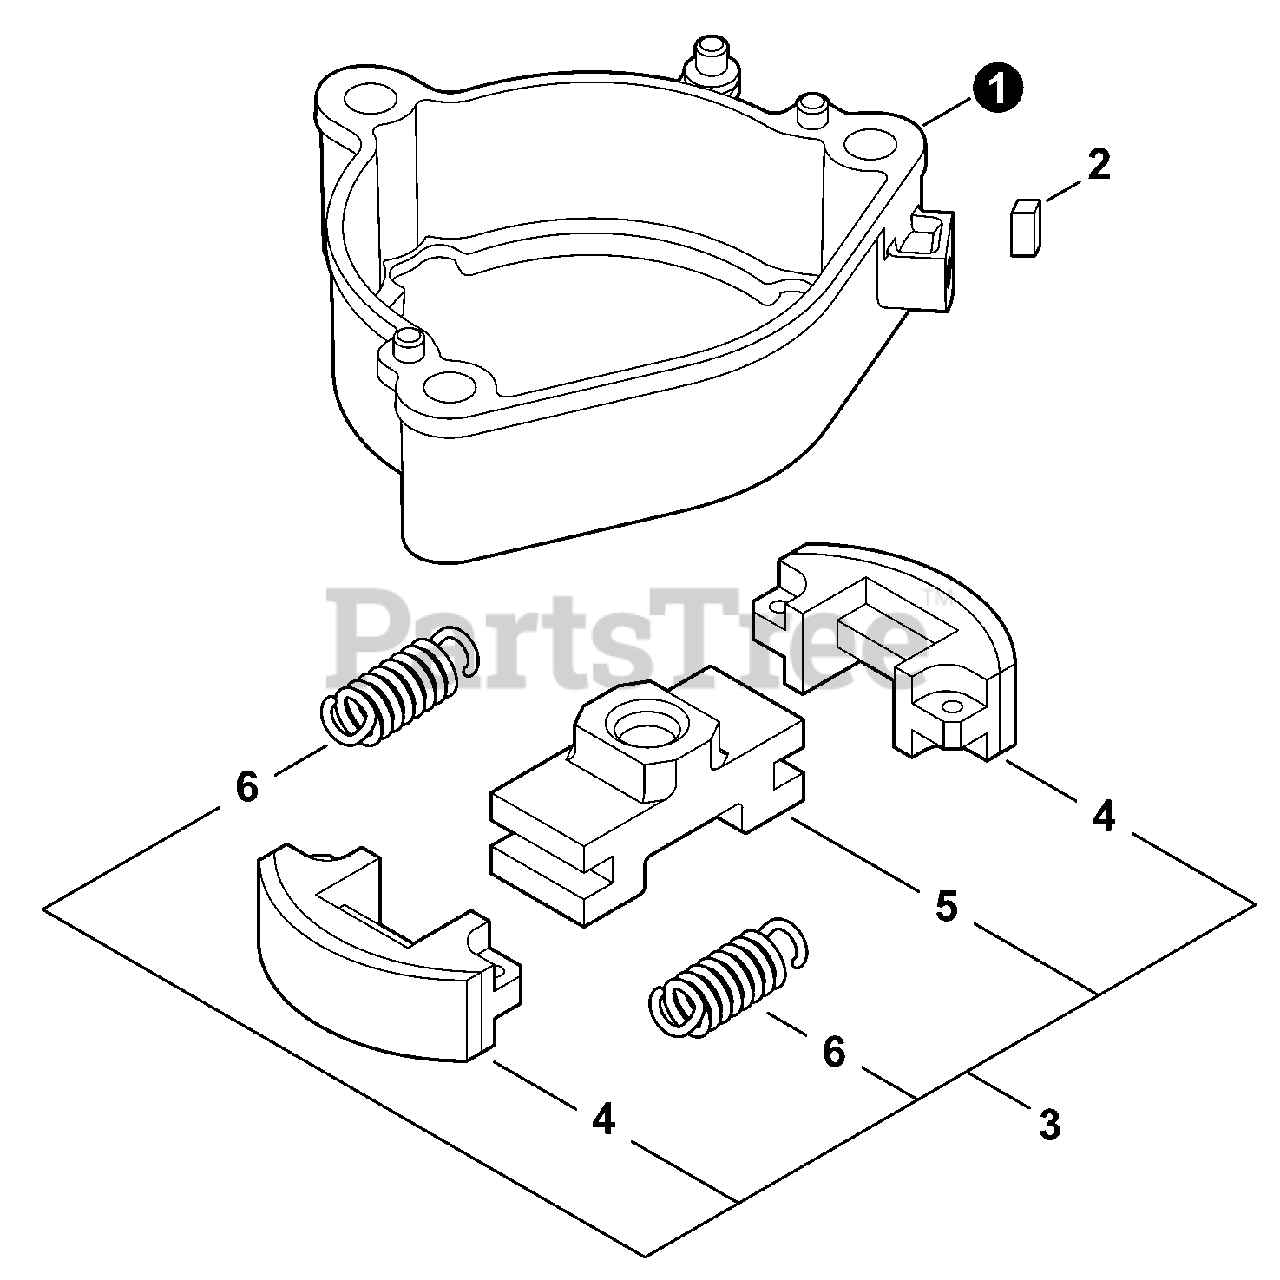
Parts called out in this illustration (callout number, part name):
1	CASE, CLUTCH
2	NUT M5
3	CLUTCH ASSY
4	SHOE SET, CLUTCH
5	HUB, CLUTCH
6	SPRING, CLUTCH
